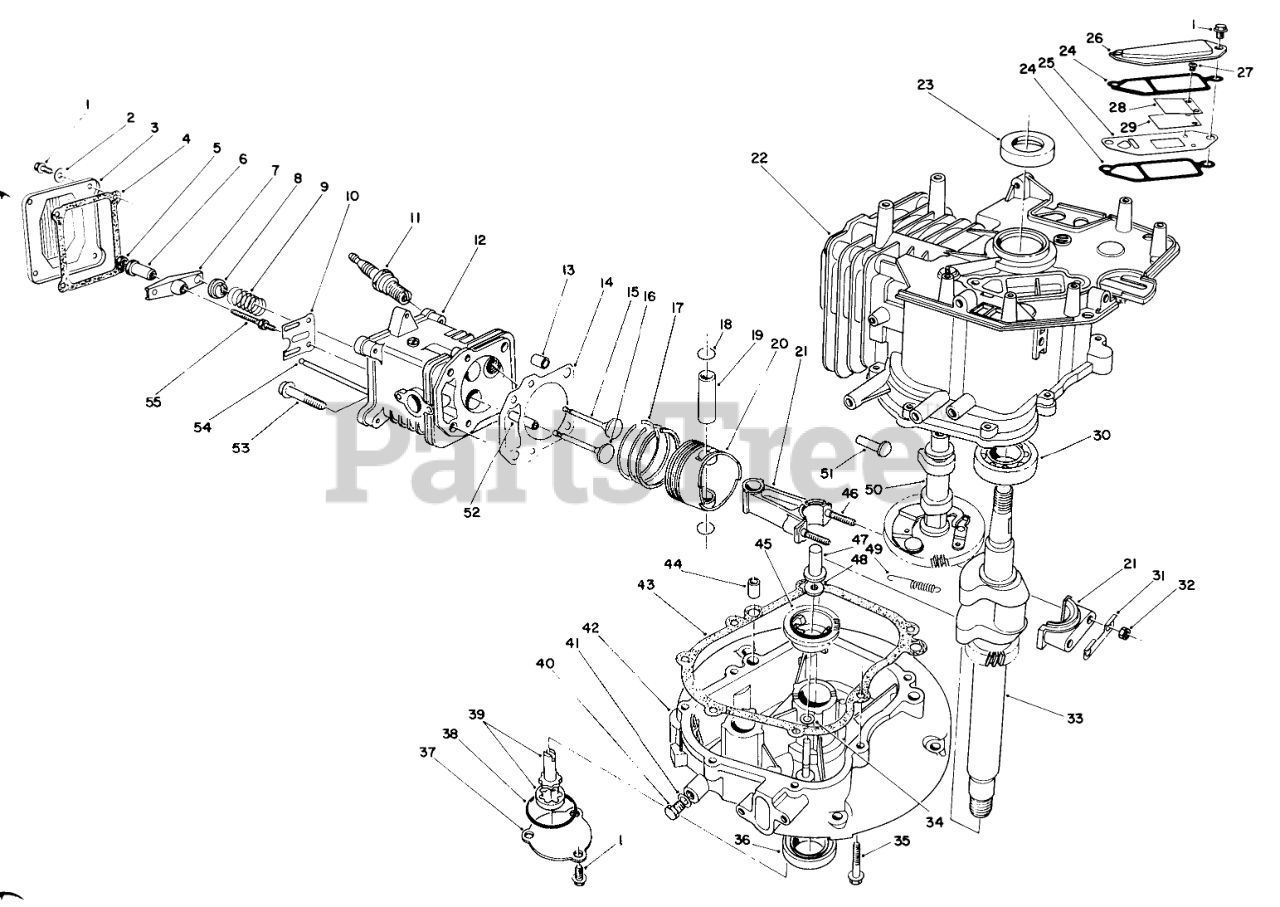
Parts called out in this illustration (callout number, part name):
2	WASHER
3	COVER
4	GASKET
6	PIVOT
8	RETAINER
9	SPRING
10	GUIDE
11	SPARK PLUG
12	Head-Cylinder Ass-y (Incl. Ref. #52)
14	GASKET
15	VALVE-EXHAUST
16	VALVE-INTAKE
17	RING SET
18	CIRCLIP
20	PISTON
21	Connection Rod Ass-y (Incl. Ref. #31, 32, 46)
22	Block-Engine (Incl. Ref. #23 & 30)
24	GASKET
25	Plate-Breather
26	COVER
27	Screw-Reed Valve
28	Retainer-Reed Valve
29	Valve-Reed
30	BEARING
31	Plate-Lock
33	CRANKSHAFT
34	WASHER
37	COVER
38	O-RING
39	OIL PUMP
40	OIL DRAIN PLUG
41	GASKET
42	Crankcase
43	GASKET
45	GOVERNOR FLYWEIGHT ASM
47	PLUNGER
48	WASHER
49	SPRING
50	Camshaft Assembly (Incl. Ref. #49)
51	TAPPET
52	GUIDE
